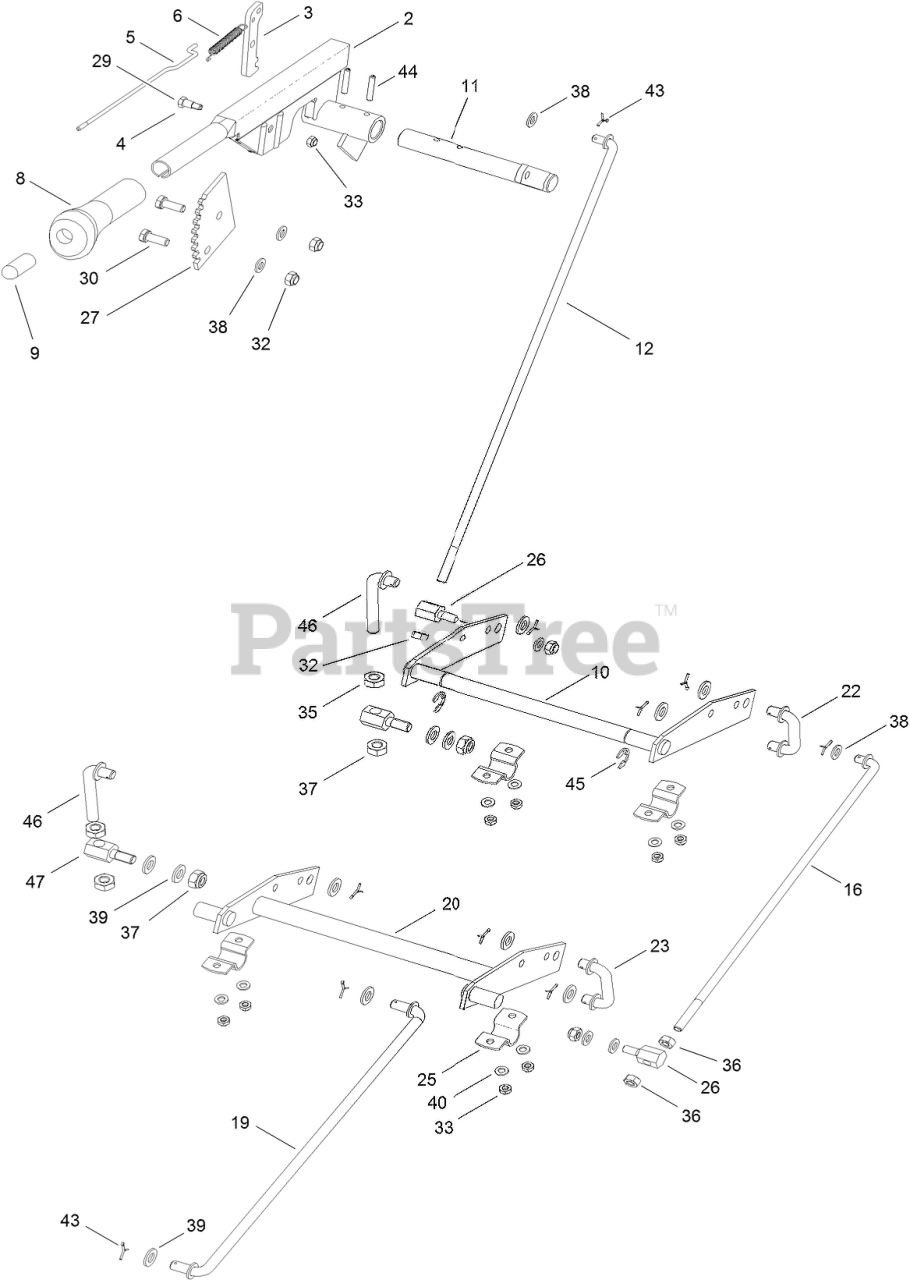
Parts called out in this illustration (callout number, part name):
2	LEVER-ARM
3	RATCHET-PLATE, PIVOT
4	BUSHING
5	ROD-CONNECTION
6	SPRING
8	GRIP-HANDLE
9	BUTTON-PLUNGER
10	HANGER-REAR
11	SHAFT-ADJUSTMENT, HEIGHT
16	ROD-LINKAGE
20	HANGER-FRONT
22	DECK LINK, U-SHAPE, 50
23	DECK LINK, U-SHAPE, 55
26	TRUNNION
27	GEAR-SEGMENT, DECK LIFT
29	SCREW-HH
30	SCREW-HH
32	NUT-LOCK, NI
33	NUT-LOCK
35	NUT-HEX
36	NUT-HEX
37	NUT-LOCK, NI
38	WASHER-PLAIN
39	WASHER-FLAT
40	WASHER
43	PIN-COTTER
44	PIN-SPRING
45	E-CLIP
46	LINK-DECK, L-SHAPE (ADJUSTABLE)
47	TRUNION
